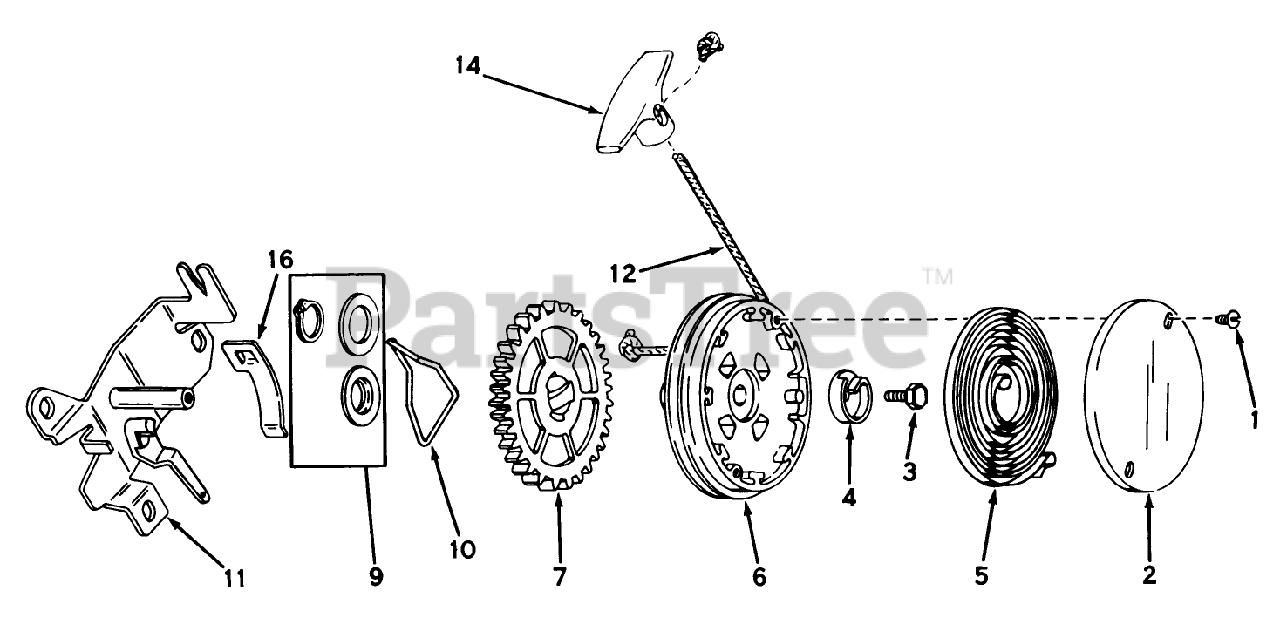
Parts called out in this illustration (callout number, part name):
1	Screw
2	Cover, Spring
3	Screw, Hex Washer Head
4	Hub Spring
5	Spring, Rewind
6	Pulley Assy. (Incl. No. 9)
9	Kit, Thrust Wash. Snap Rg.
10	Brake
11	Bracket Assy., Mounting
12	Rope-Starter
14	Handle-Starter
16	Clip Rope
